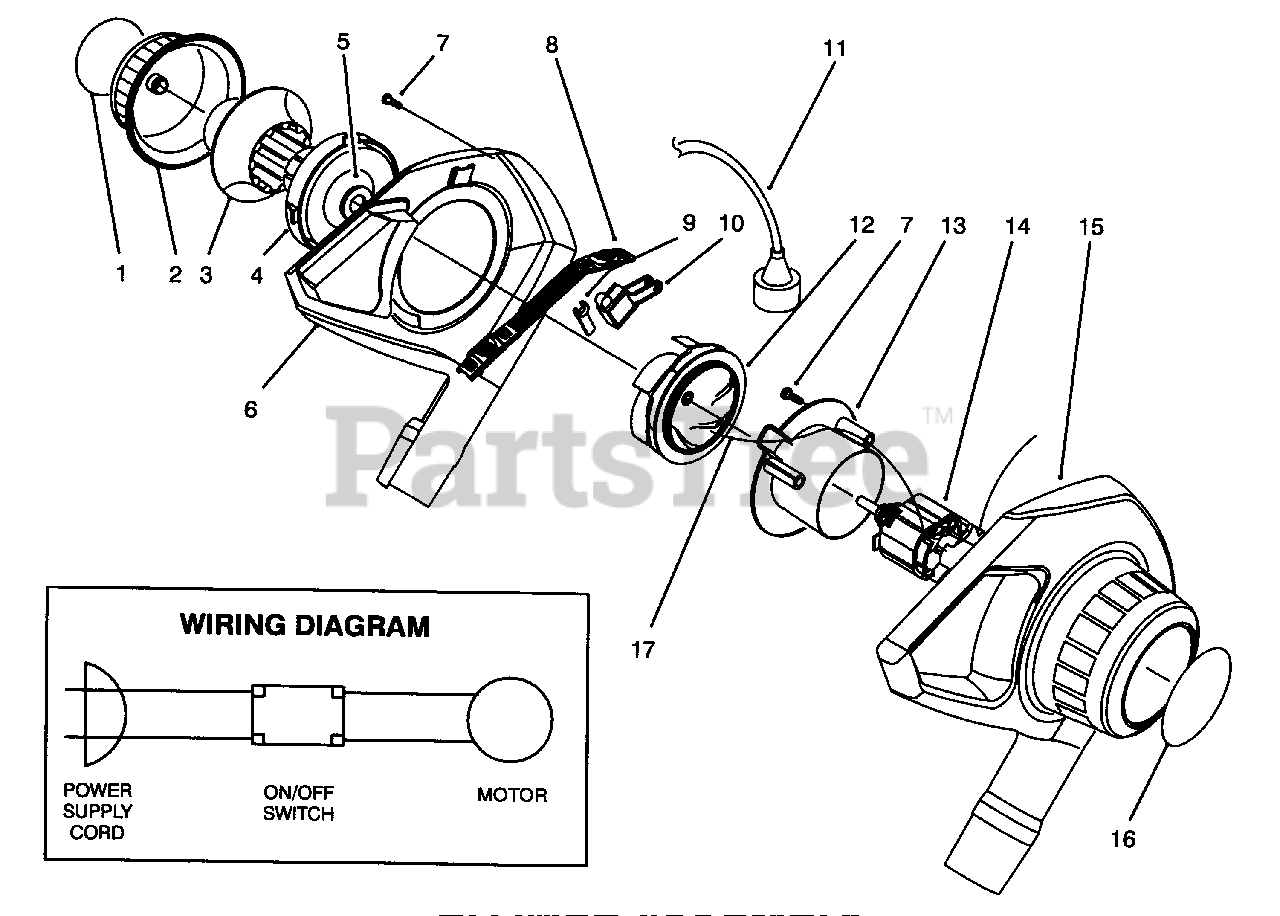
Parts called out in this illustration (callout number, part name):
1	Decal-Choke
2	Cover-Choke
3	Ring-Choke
4	Base-Choke
5	Clip-Retainer
6	Housing Assembly-R.H.
7	Screw
8	Bar-Switch
9	Lever-Actuating
11	Cord-Power
12	Impeller Assembly
13	Plate-Retaining
15	Housing-L.H.
16	Decal-Motor Cover
